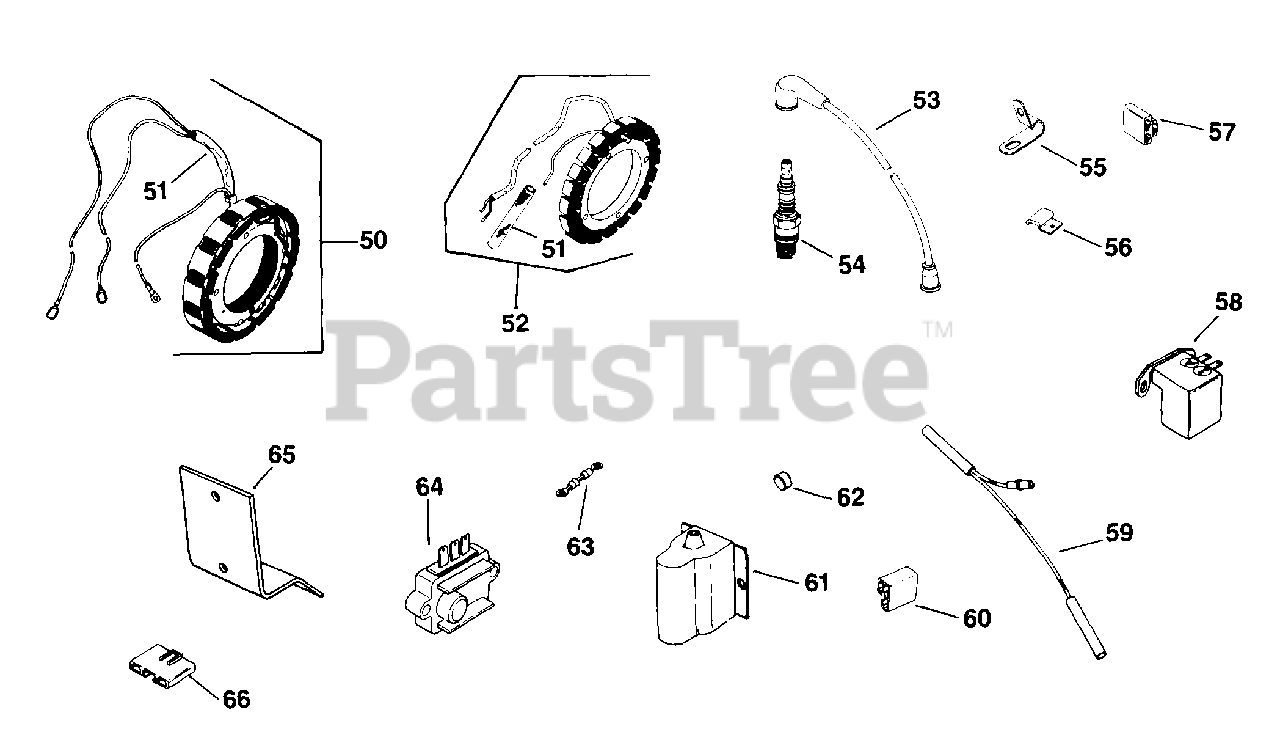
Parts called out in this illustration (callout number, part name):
50	KIT, STATOR - DISCONTINUED
51	Sleeve
51	SLEEVE - DISCONTINUED
51	SLEEVE DISCONTINUED
53	KIT, HI-TENSION
54	SPARK PLUG USE 25 132 10-S
59	TRIGGER LEAD - DISCONTINUED
62	PLUG, CUP 3/16" USE 25 139 51-S
64	REGULATOR
65	BRACKET - DISCONTINUED
66	CONNECTOR, BODY (KM)-USE 25 155 41-S
